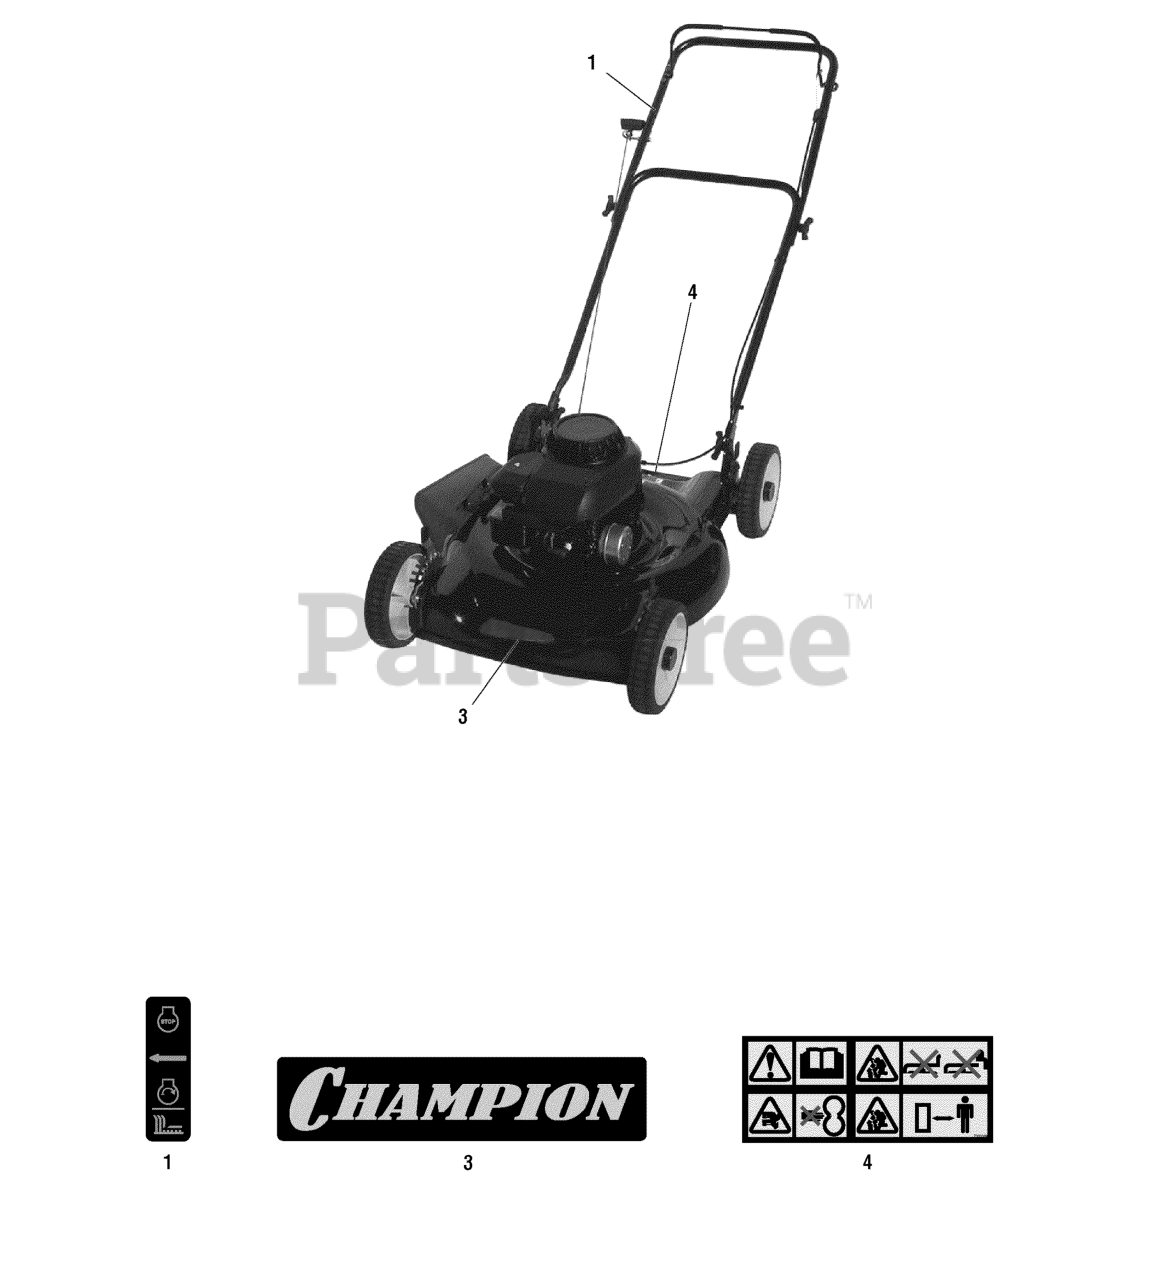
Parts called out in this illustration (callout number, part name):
1	DECAL, OPC BAIL
3	DECAL, Champion
4	DECAL, Warning, Multi Panel
